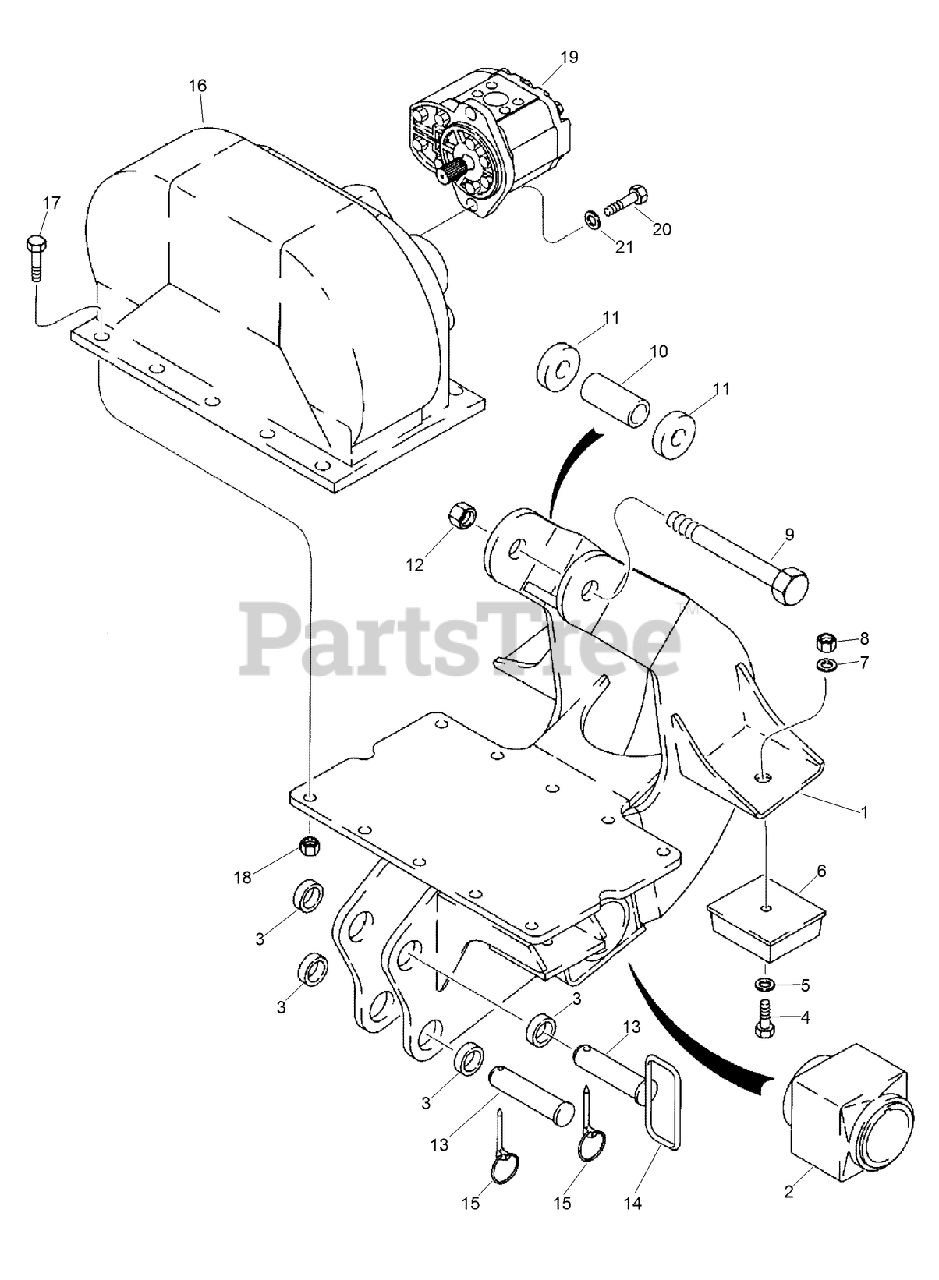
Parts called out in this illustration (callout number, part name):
1	FRAME-plow gearbox mounting
2	JOINT-CENTER, BONDED RUBBER
3	BUSHING-plow frame
4	BOLT
5	WASHER-FLAT
6	BUMPER
7	WASHER-FLAT
8	NUT-HEX
9	BOLT-hex, 1 NC x 7 inch
10	SPACER-bushing, 38 mm OD x 87 mm long
11	BUSHING-cylinder mounting
13	PIN-clevis, 1-1/8 x 4-7/8 inch long
14	PIN-with handle, 28 x 114 mm, plow blade
15	PIN-KLIK
16	BOX-SHAKER
18	NUT-HEX
19	MOTOR ASM-plow
20	SCREW-HH
